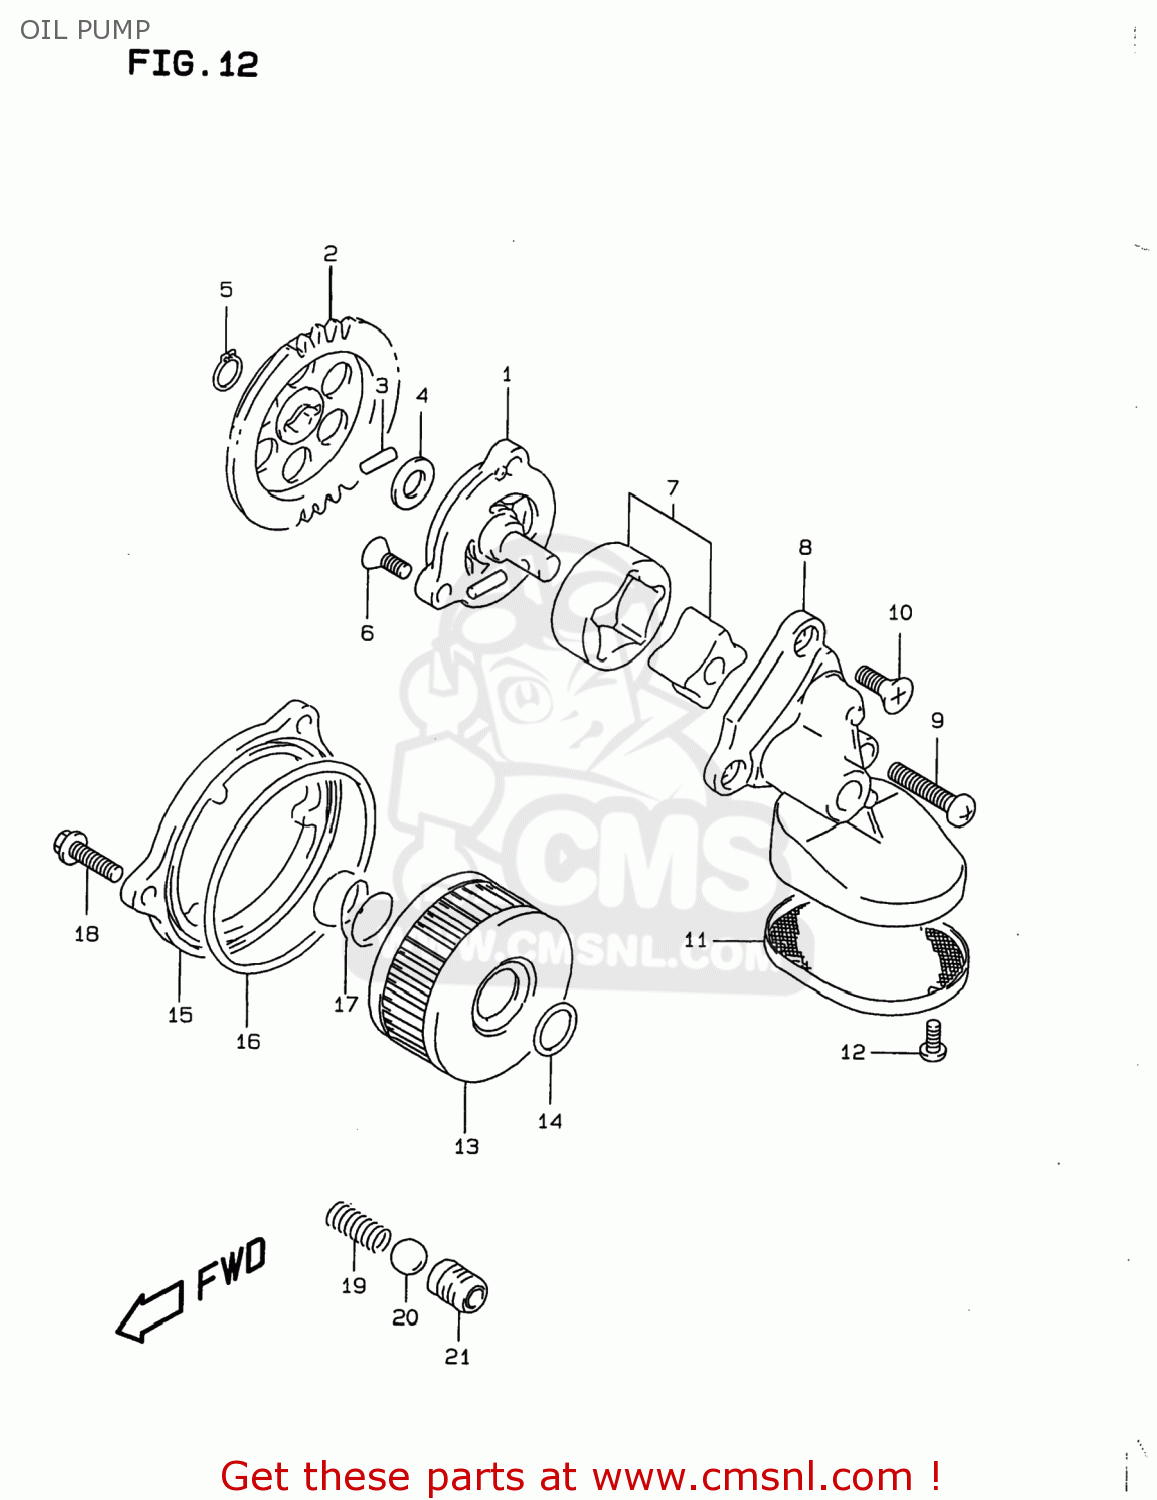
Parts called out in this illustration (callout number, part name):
1	PUMP ASSY,ENGINE OIL NO.1
2	GEAR,OIL PUMP DRIVEN (N
3	PIN(4X15.8)
4	SHIM(10X18X0.5)
5	CIRCLIP,10MM
6	SCREW ,6X16
7	ROTOR SET,OIL PUMP,NO.2
8	COVER,OIL PUMP NO.2
9	SCREW 6X30
10	SCREW ,6X16
11	STRAINER,OIL PUMP NO.2
12	SCREW
13	FILTER ASSY,ENGINE OIL
14	O RING(D:2.4,ID:15.8)
15	CAP,OIL FILTER
16	O RING(D:2.4,ID:73)
17	SPRING
18	SCREW
19	SPRING
20	BALL
21	SEAT,OIL CHECK VALVE
